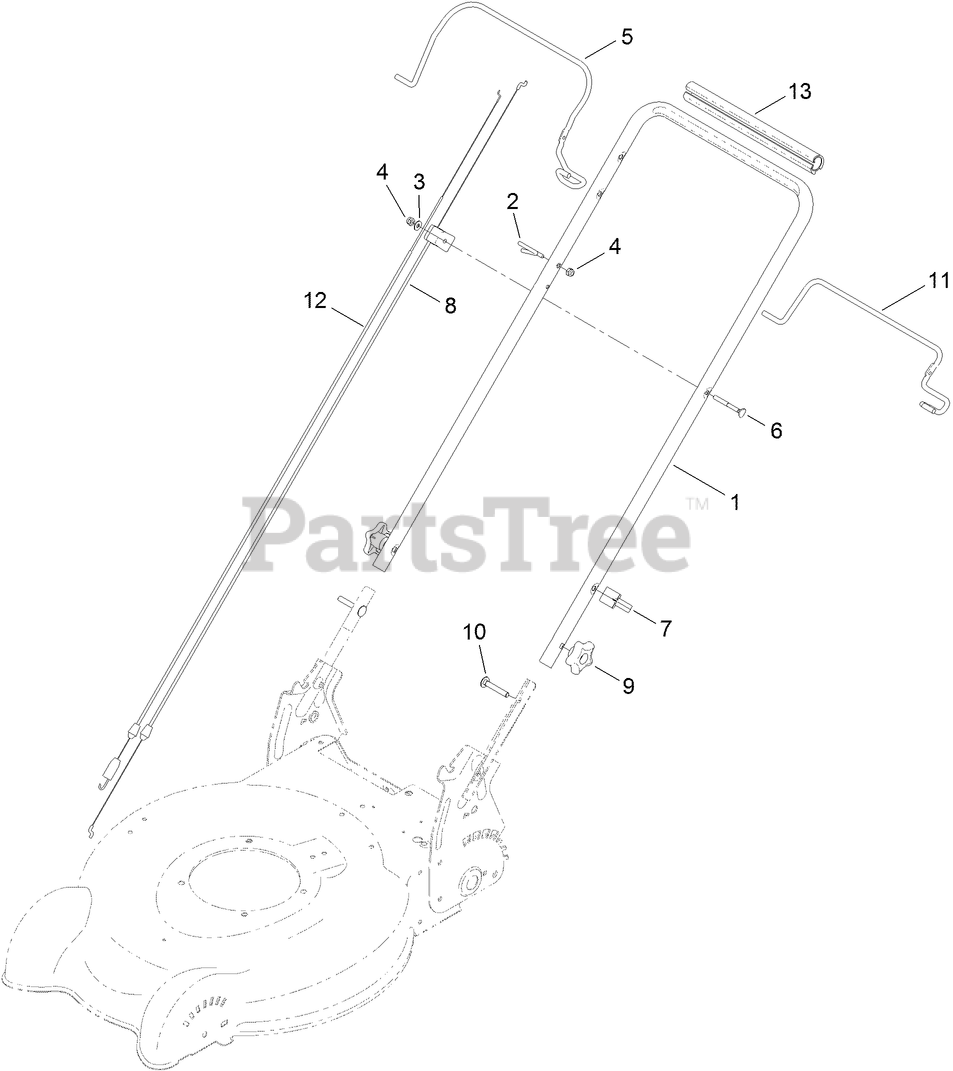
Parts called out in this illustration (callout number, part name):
1	HANDLE-UPPER
2	GUIDE-ROPE
3	WASHER-FLAT
4	NUT-LOCK, NI
5	BAIL-BRAKE
6	SCREW-HANDLE
7	GUIDE-CABLE
8	CABLE-BRAKE
9	KNOB-HANDLE
10	BOLT-CARR
11	BAIL-TRACTION, 2-BAIL FLAT
12	CABLE-TRACTION
13	GRIP-HANDLE, COMFORT
